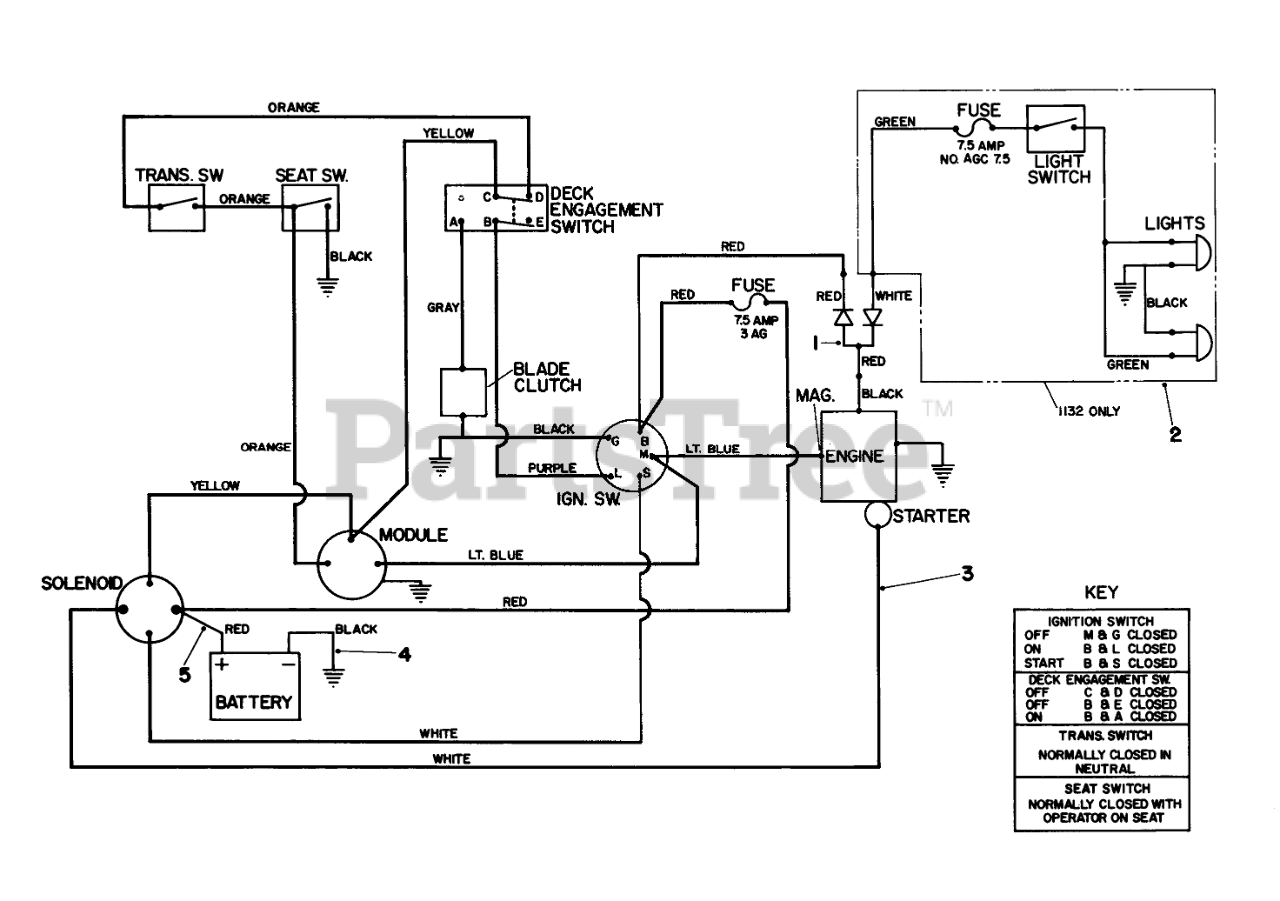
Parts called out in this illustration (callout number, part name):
1	WIRE HARNESS WIRE
2	WIRE HARNESS
3	WIRE HARNESS
4	WIRE ASM
5	WIRE ASM
